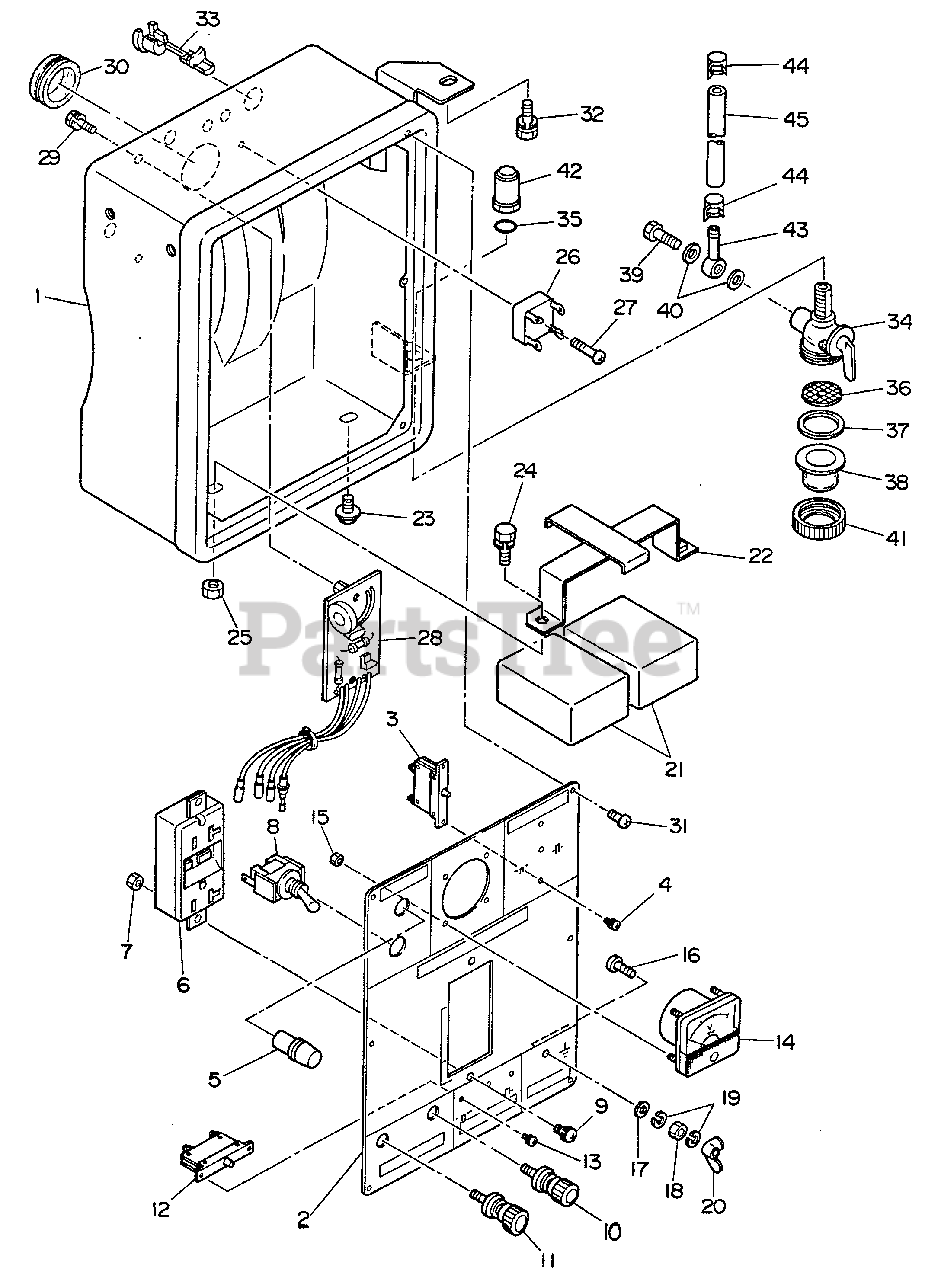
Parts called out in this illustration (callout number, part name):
1	CONTROL BOX ASSY
2	CONTROL PANEL ASSY
3	CIRCUIT BREAKER
4	SCREW
5	LAMP, NEON
6	AC RECEPTACLE - 125V-20A, GFCI
7	NUT
8	SWITCH
9	SCREW
10	BOLT, TERMINAL - RED
11	BOLT, TERMINAL - BLACK
12	CIRCUIT BREAKER - 10A DC
13	SCREW
14	AC VOLT METER
15	NUT
16	SCREW
17	WASHER
18	NUT
19	LOCKWASHER
20	WINGNUT
21	CONDENSER
22	CONDENSER BRACKET ASSY
23	BOLT - FLANGE
24	BOLT
25	NUT
26	DIODE STACK ASSY
27	SCREW -- TAPPING
28	IDLE CONTROL UNIT
29	SCREW
30	GROMMET
31	SCREW -- TAPPING
32	BOLT
33	GROMMET
34	FILTER, FUEL
35	O-RING
36	FILTER
37	SEAL
38	CUP
39	BOLT
40	WASHER
41	LOCKNUT
42	CONNECTOR
43	BOLT, BANJO
44	CLAMP, HOSE
45	RUBBER PIPE (4.5 dia. X 11 dia. X 160mm)
